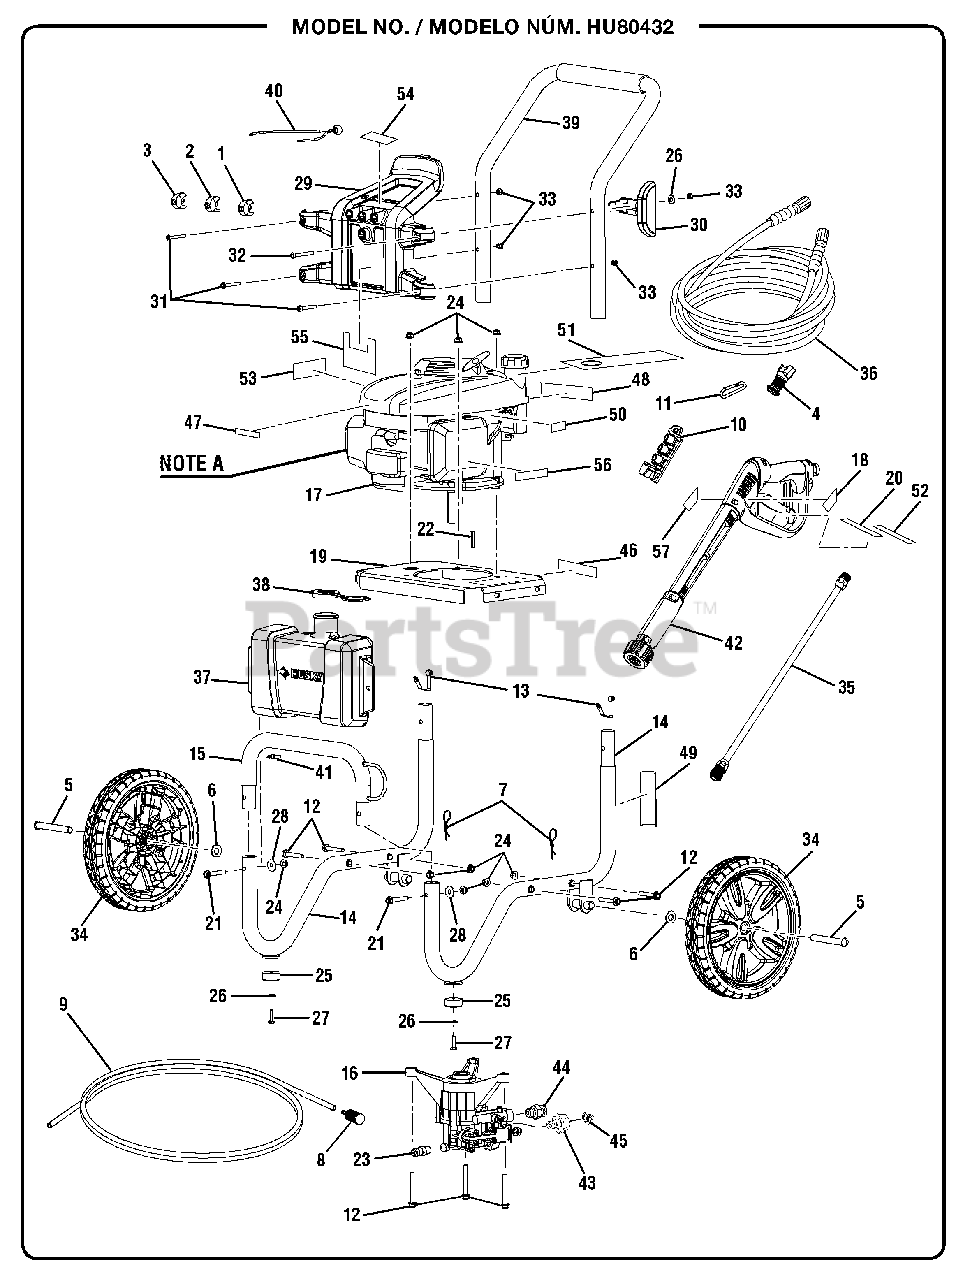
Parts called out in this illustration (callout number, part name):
1	0° Nozzle
2	40° Nozzle
3	25° Nozzle
4	Soap Blaster Nozzle
5	Axle
6	Washer (1/2 in.)
7	Hitch Pin
9	Injection Hose
10	Storage Holder
11	Spring Clip
12	Bolt w/Washer (M8 x 55 mm Hex Hd.)
13	Lock Button w/Spring Clip
14	Main Frame Assembly
15	Front Frame
16	Pump
17	Engine
18	Trigger Handle Logo Label
19	Engine Plate
20	Wand Label (Fr./Sp.)
21	Bolt (M8 x 50 mm)
22	Output Shaft Key
23	Thermal Release Valve
24	Lock Nut (M8 x 1-1/4 in.)
26	Washer (1/4 in.)
27	Bolt (1/4-20 x 1 mm Hex Hd.)
28	Washer (5/16 in.)
29	Hose and Nozzle Holder
30	Wand Holder
31	Screw (1/4-20 x 1.85 in., Torx)
32	Screw (1/4-20 x 2.27 in., Torx)
33	Lock Nut (1/4-20)
34	Wheel (12 in. x 2 in.)
35	Spray Wand
36	High Pressure Hose
37	Soap Tank
38	Soap Tank Cap
39	Handle Assembly
40	Bungee Cord and Bead Assembly
41	Injection Hose Holder
42	Trigger Handle Assembly
43	Inlet Tube
44	Outlet Tube
45	Filter Screen
46	Data Label
47	Honda Logo Label
48	Warning Label
49	Pump Quick Start Label
50	Fuel Valve Label
51	Engine Oil Fill Label
52	Wand Label
53	Hot Muffler Label
54	Nozzle Label
55	Performance Label
56	Engine Quick Start Label
57	Trigger Handle Warning Label
